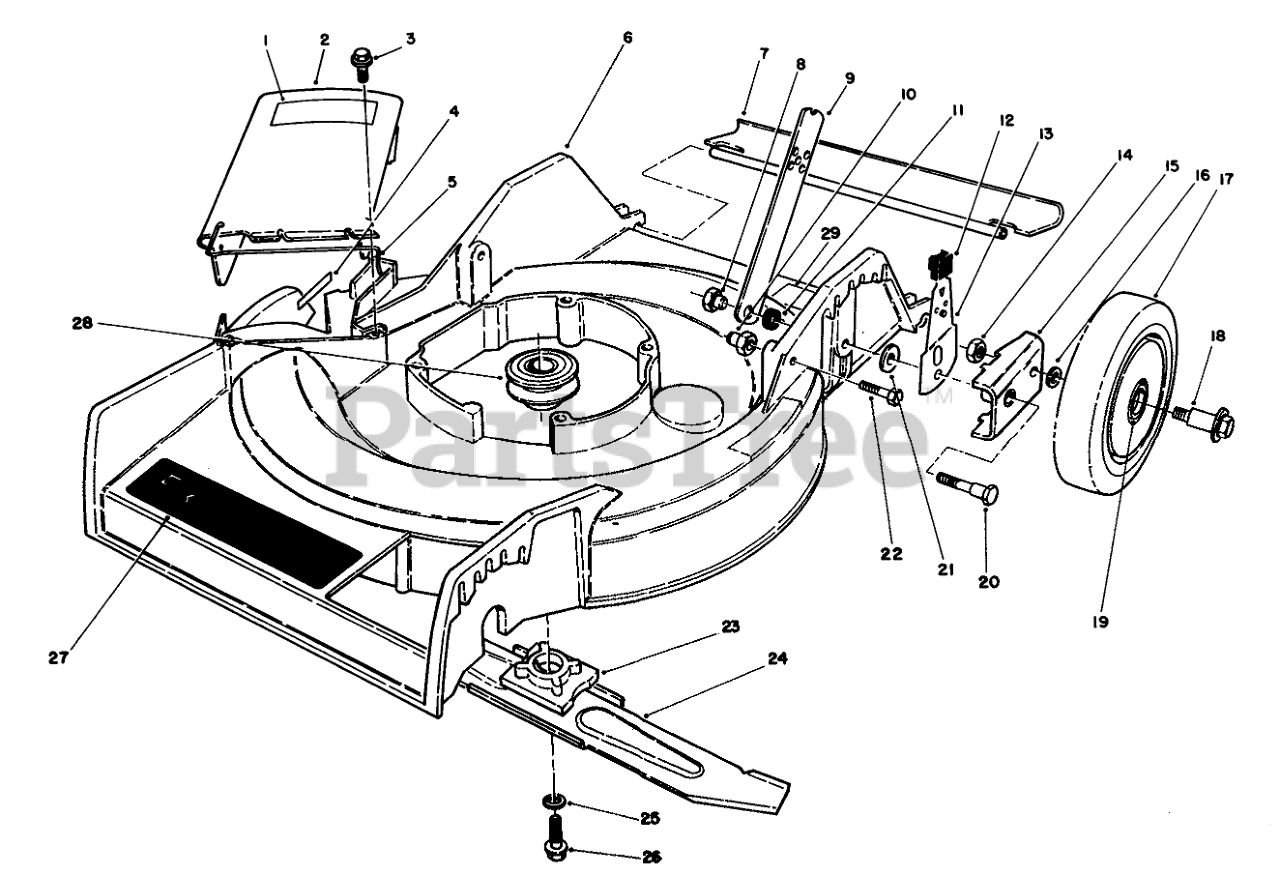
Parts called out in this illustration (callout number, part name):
1	DECAL - DANGER DEFL
2	Deflector (Incl. Ref. #1 & 5)
3	SCREW-HWH
4	DANGER DECAL
5	SPRING HINGE
6	Housing (Incl. Ref. #4)
7	SHIELD - TRAILING
8	HANDLE PIVOT NUT
9	HANDLE LATCH
10	HANDLE PIVOT NUT
11	SPACER
12	KNOB-ARM
13	SPRING ARM ASSEMBLY
14	Nut
15	HP PIVOT ARM ASM
16	WASHER
17	Wheel & Tire Assembly (Incl. Ref. #19)
18	BOLT-WHEEL
19	BUSHING
20	PIVOT SCREW
21	PIVOT WASHER
22	SCREW-HH
23	BLADE RETAINER
24	Blade
25	WASHER-LOCK
26	SCREW-HH
27	DECAL - SP DECK
28	PULLEY-DRIVER
29	Decal-Noise Rating
